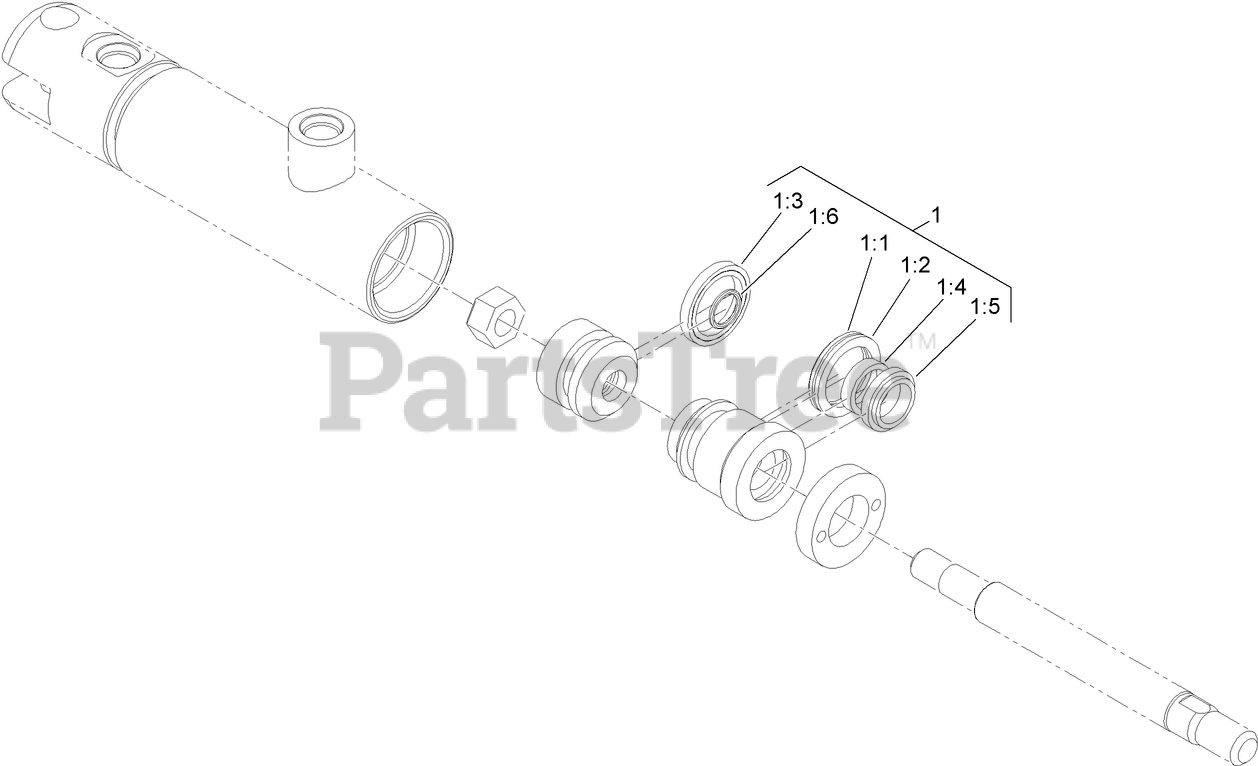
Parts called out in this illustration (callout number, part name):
1	SEAL KIT
1:1	O-RING
1:2	RING-BACKUP
1:3	SEAL-P S P
1:4	SEAL-B S
1:5	SEAL-DUST
1:6	O-RING
